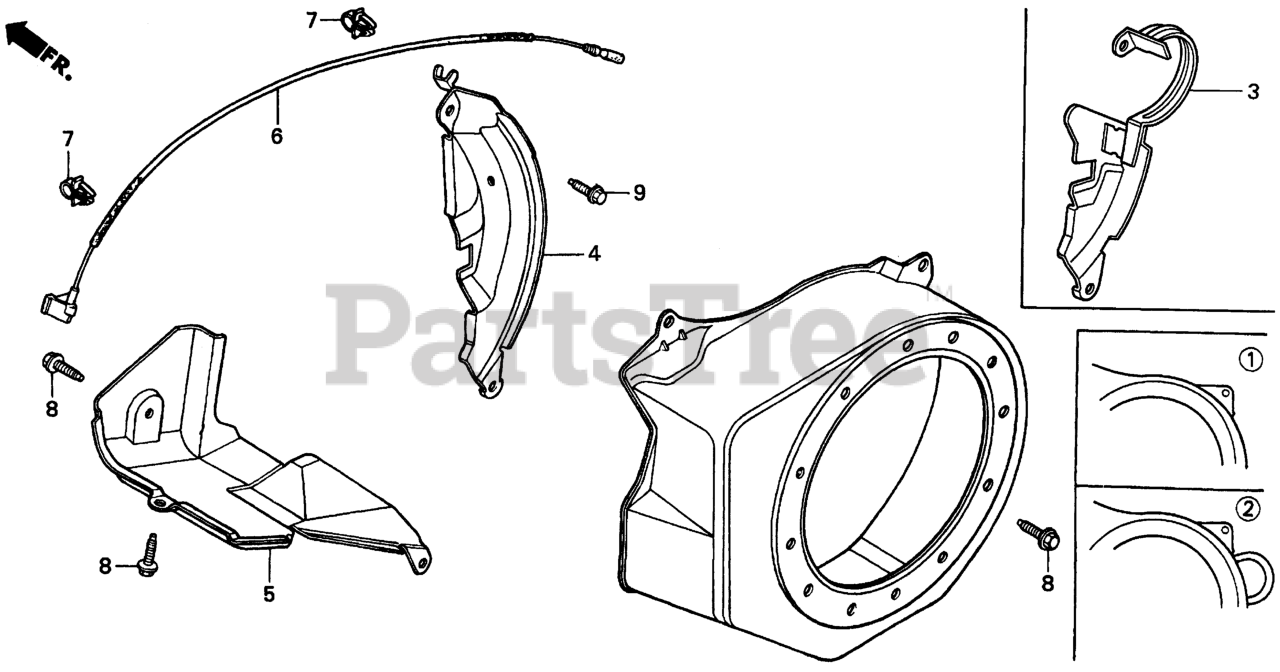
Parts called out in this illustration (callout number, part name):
1	COVER, FAN *R280* (POWER RED)
4	PLATE, SIDE (LAMP)
5	SHROUD
6	WIRE, STOP SWITCH (370MM)
8	BOLT, FLANGE (6X12) (CT200)
9	BOLT, FLANGE (6X20) (CT200)
